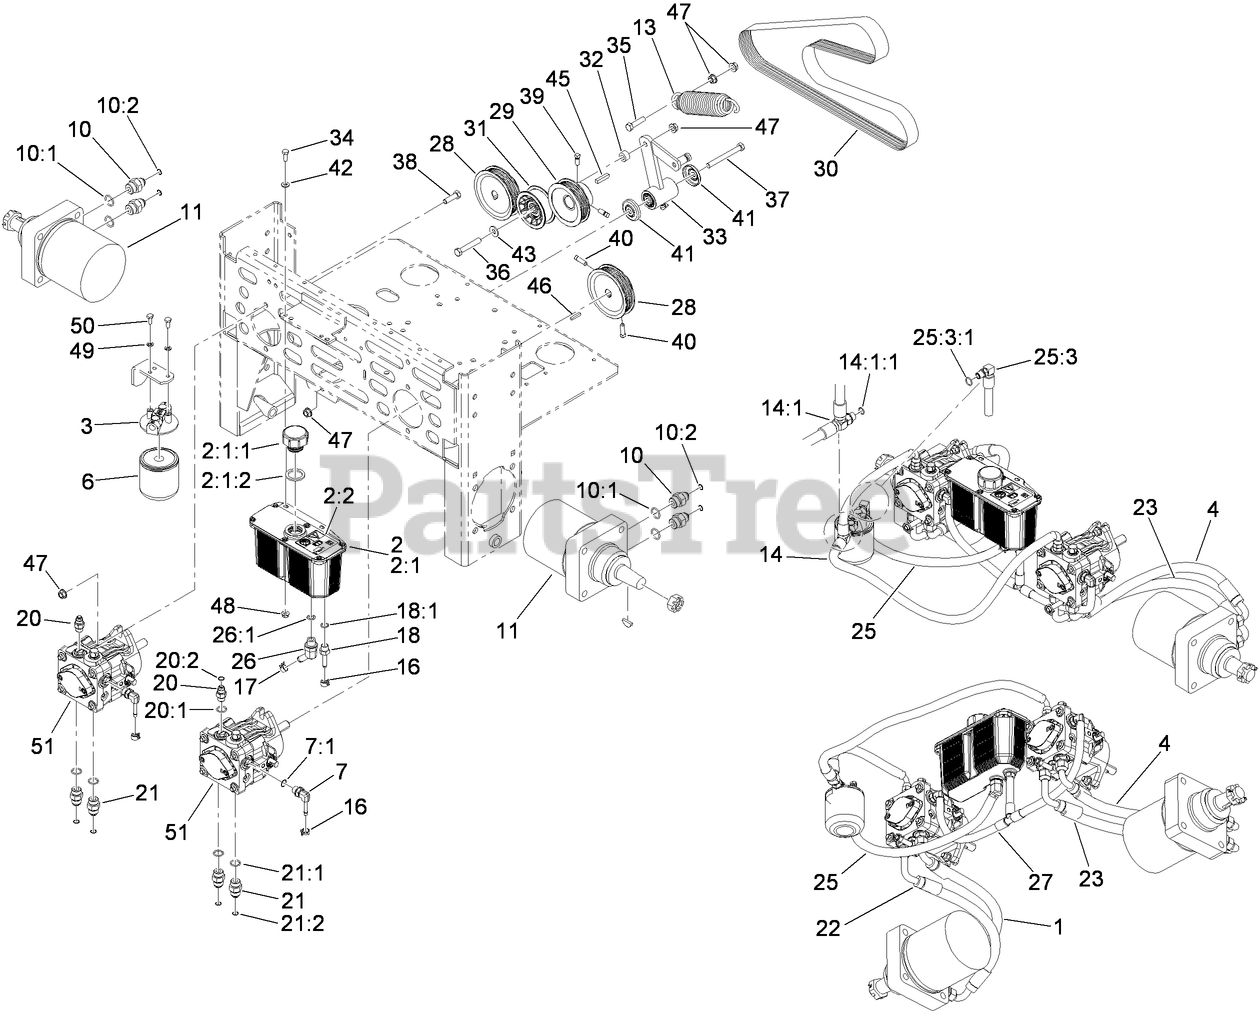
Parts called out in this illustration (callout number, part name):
1	HYD HOSE ASM
2	HYD RESERVOIR ASM
2:1	Reservoir-HYD
2:1:1	CAP-RESERVOIR, HYD
2:1:2	GASKET-CAP
2:2	DECAL-WARNING
3	HEAD-FILTER
4	HYD HOSE ASM
6	FILTER-OIL, HYD
6	FILTER-OIL, HYD (WINTER)
7	ELBOW-90 DEG
7:1	O-RING
10	Fitting-Straight
10:1	O-RING
10:2	O-Ring
11	MOTOR-WHEEL
13	EXTENSION-SPRING
14	HYD HOSE ASM
14:1	ADAPTER-RUN, TEE
14:1:1	O-RING
16	Clamp-Hose
17	Clamp-Hose
18	Adapter-Straight
18:1	O-RING
20	FITTING-STRAIGHT
20:1	O-Ring
20:2	O-RING
21	FITTING-STRAIGHT
21:1	O-RING
21:2	O-Ring
22	HYD HOSE ASM
23	HYD HOSE ASM
25	HYD HOSE ASM
25:3	FITTING-BARBED, 90 DEG
25:3:1	O-RING
26	FITTING-BARBED, 45 DEG
26:1	O-RING
27	HYD Hose ASM
28	SHEAVE
29	SHEAVE
31	PULLEY-FLAT IDLER
32	SPACER
33	PUMP IDLER ASM
34	SCREW-HH
35	SCREW-HH
36	SCREW-HH
37	SCREW-HH
38	SCREW-HH
39	SCREW-SET
40	SCREW-SET
41	GUARD-TOP
42	WASHER-FLAT
43	WASHER-FLAT
45	KEY-SQUARE
46	KEY-SQUARE
47	NUT-HHF, WHIZ
48	NUT-HF
49	WASHER-LOCK
50	SCREW-HH
51	PUMP-HYD
